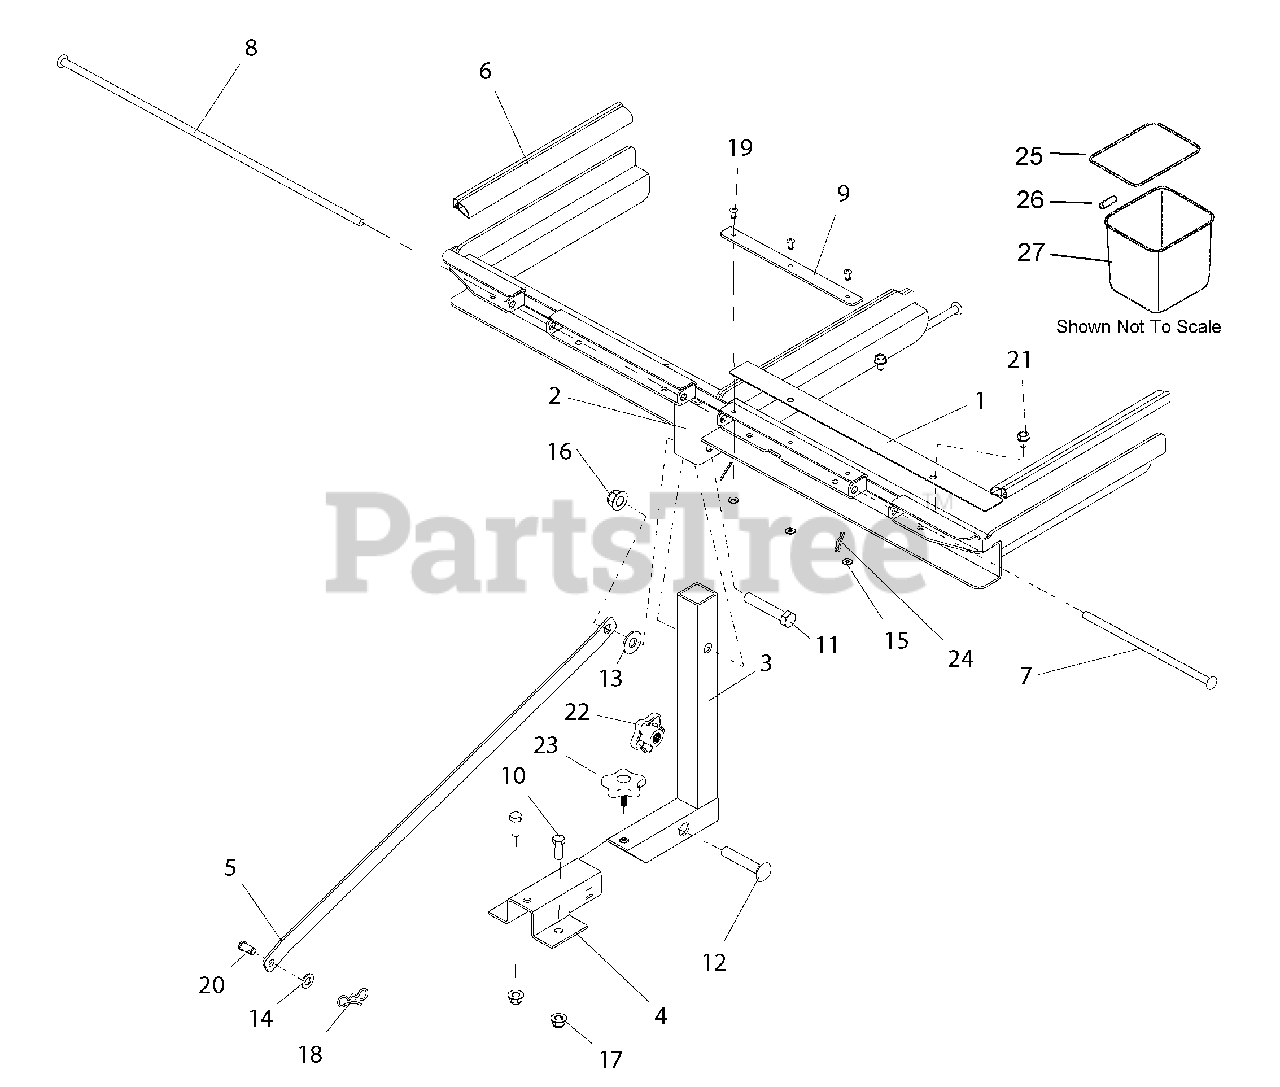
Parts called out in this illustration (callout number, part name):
1	BRKT-BAGGER OVERLAP
2	ASS'Y, BAGGER FRAME UPPER
3	BRKT, RECEIVER SLEEVE INSERT
4	BRKT, RECEIVER LOWER
5	BRKT, BAG FRAME SUPPORT BAR
6	SEAL, BULK
7	PIN, BAGGER HINGE (L)
8	PIN, BAGGER HINGE (R)
9	SEAL, HINGE
10	@BLT-HEX .38-16X1.00 GR5 YWZC
11	@BLT-HEX .50-13X2.75 GR5 YWZC
12	BLT-RDHDSQNK .50-13X2.75 G5YZ
13	WSHR-FL-STL .531X1.250X.10 YWZ
14	@WSHR-FL-STL.406X.812X.065 YWZ
15	@WSHR-FL-STL.219X.50X.049 YWZC
16	@NUT-LK-NYL-FLG .50-13 YWZC
17	@NUT-LK-NYL-FLG .38-16 YWZC
18	PIN,BOW TIE LOCKING .091X1.875
19	RVT-POP.187X.527 DOME ST
20	PIN-CLEV .38X.75 YWZC
21	@SCR-TAP .31-18X.50 HWH TR YWZ
22	KNOB, WING
23	KNOB, WING STUDDED
24	PIN-HAIR, ENDRIES #25 YWZC
25	FRAME, ZOOM BAG
26	HOSE, .38 X.50 X 3.00 VINYL
27	BAG, MESH ZOOM
